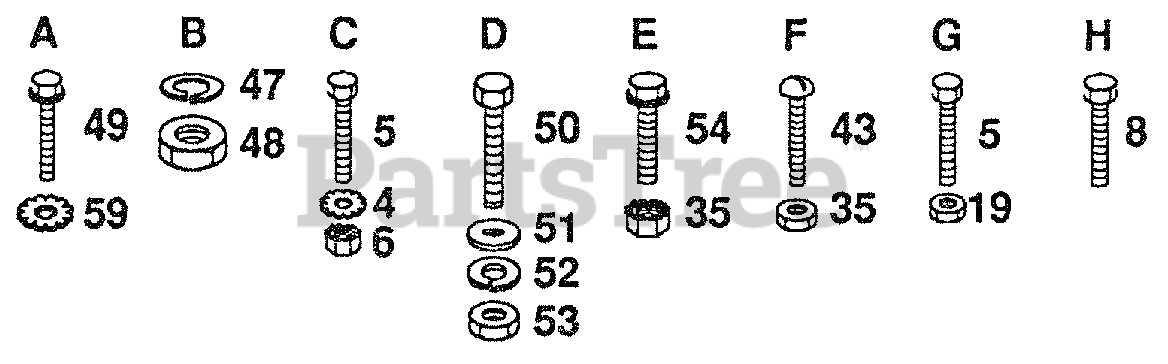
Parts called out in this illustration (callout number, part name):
4	Washer, Lock Ext. Tooth 1/4
5	Bolt, Hex 1/4-20 x 1/2
6	Nut, Hex Keps. 1/4-20
8	Screw #10-24 x 1/2
19	Nut, Crownlock 1/4-20
35	Nut Keps No. 10-32
43	Screw-Slot-Pan HD 10-32 x 1/2
47	Lockwasher 1/4
48	Nut, Hex Jam 1/4 - 20
49	Screw- Hex Washer Hd. Cutting 1/4-20 x 1/2
50	Bolt - Hex Hd. 1/4 - 20 x 3/4
51	Washer 9/32 x 5/8 x 16 Ga.
52	Lockwasher 1/4
53	Nut-Hex 1 /4-20
54	Screw- Hex Washer Hd. No. 10-24 x 1 - 1/2
59	Lockwasher, Ext. Tooth 3/8
